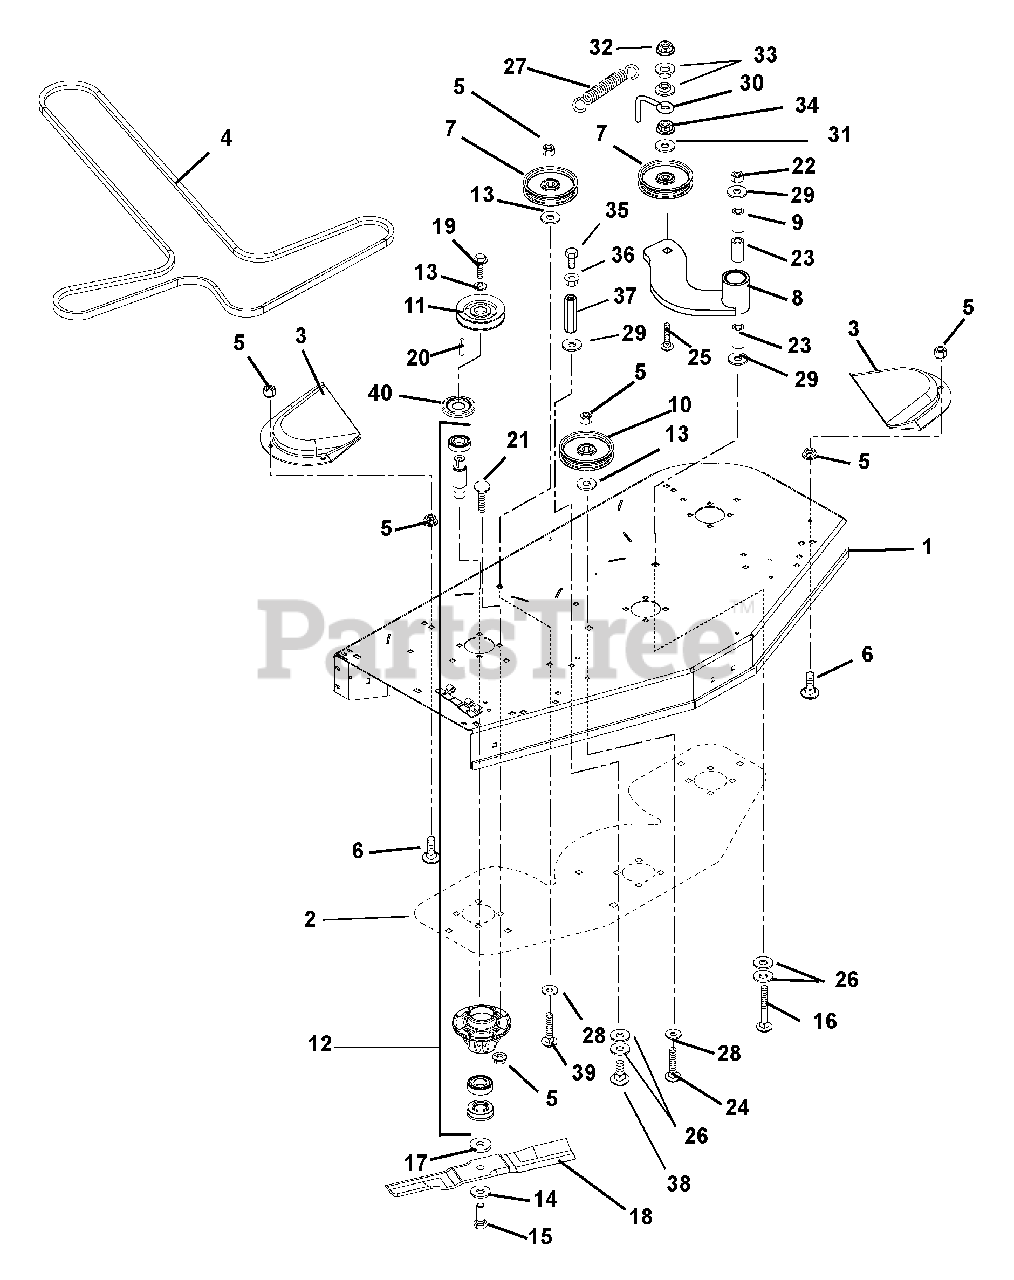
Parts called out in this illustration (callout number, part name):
1	WMT, 40" DECK
1	WMT, 44" DECK
1	WMT, 48" DECK
1	WMT, 52" DECK
2	PLATE, 40" DOUBLER
4	HEX BELT, BB-WRAPPED
4	V-BELT, HA-WRAPPED
4	BELT,HA WRAPPED
5	@NUT-LK-NYL-FLG .38-16 YWZC
6	@BLT-RDHDSQNK .38-16X1.25 G5YZ
7	IDLER, FLAT .38X4.00X1.06
8	WMT, IDLER ARM
9	BSHG, SPCR .502X.997X2.03 PM
10	PULLEY, IDLER 4.00
11	SHEAVE, SPINDLE - 4.00 DIA.
11	SHEAVE, SPINDLE - 4.25 DIA.
11	SHEAVE, SPINDLE - 4.50 DIA.
11	SHEAVE, 4.25 DIA A-SECTION
11	SHEAVE, 4.75 DIA A-SECTION
12	ASSEMBLY, SPINDLE
13	WSHR,FLT STL.406X1.50X.245YWZC
14	WSHR-BLVL .669X1.535X.138
15	BLT-HEX .62-18X1.75 GR8 YWZC
16	@BLT-RDHDSQNK .50-13X3.50 G5YZ
17	WSHR-FLT .640X1.75X.250 YWZC
18	MOWER BLADE, 13.94"
18	BLADE, 15.50"
18	BLADE, MOWER (16.19")
18	BLADE, MOWER (18.00")
18	BLADE, MULCH 15.50"
18	BLADE, MULCH 13.88
19	BLT-HEX .38-16X1.00 YZ GR8
20	KEY, SQ .25 X .38 X .25
21	@BLT-RDHDSQNK .38-16X1.50 G5YZ
22	@NUT-LK-TOP-FLG .50-13 YWZC
23	BRG, 1.00 X 1.12 X .75
24	@BLT-RDHDSQNK .38-16X2.00 G2YZ
25	@BLT-RDHDSQNK .38-16X3.00 G5YZ
26	WSHR-FL-STL.755X1.375X.062YWZC
27	EXTENSION SPRING
28	@WSHR-FL-STL.563X1.38X.109YWZC
29	WSHR-FL-STL .515X1.625X.250 YZ
30	BELT FINGER
31	WSHR-FL-STL .406X1.00X.188 YWZ
32	@NUT-LK-TOP-FLG .38-16 YWZC
33	BSHG-FLG .406X.88X.270X.140
34	NUT-SPIRALOCK-FLG .50-13 PLN
35	@BLT-HEX .50-13X2.00 GR5 YWZC
36	@NUT-HEX .50-13 YWZC
37	NUT, COUPLING 1/2-13X1.75 YWZC
38	@BLT-RDHDSQNK .50-13X1.25 G5YZ
39	@BLT-RDHDSQNK .38-16X2.75 G5YZ
40	DUST CAP
